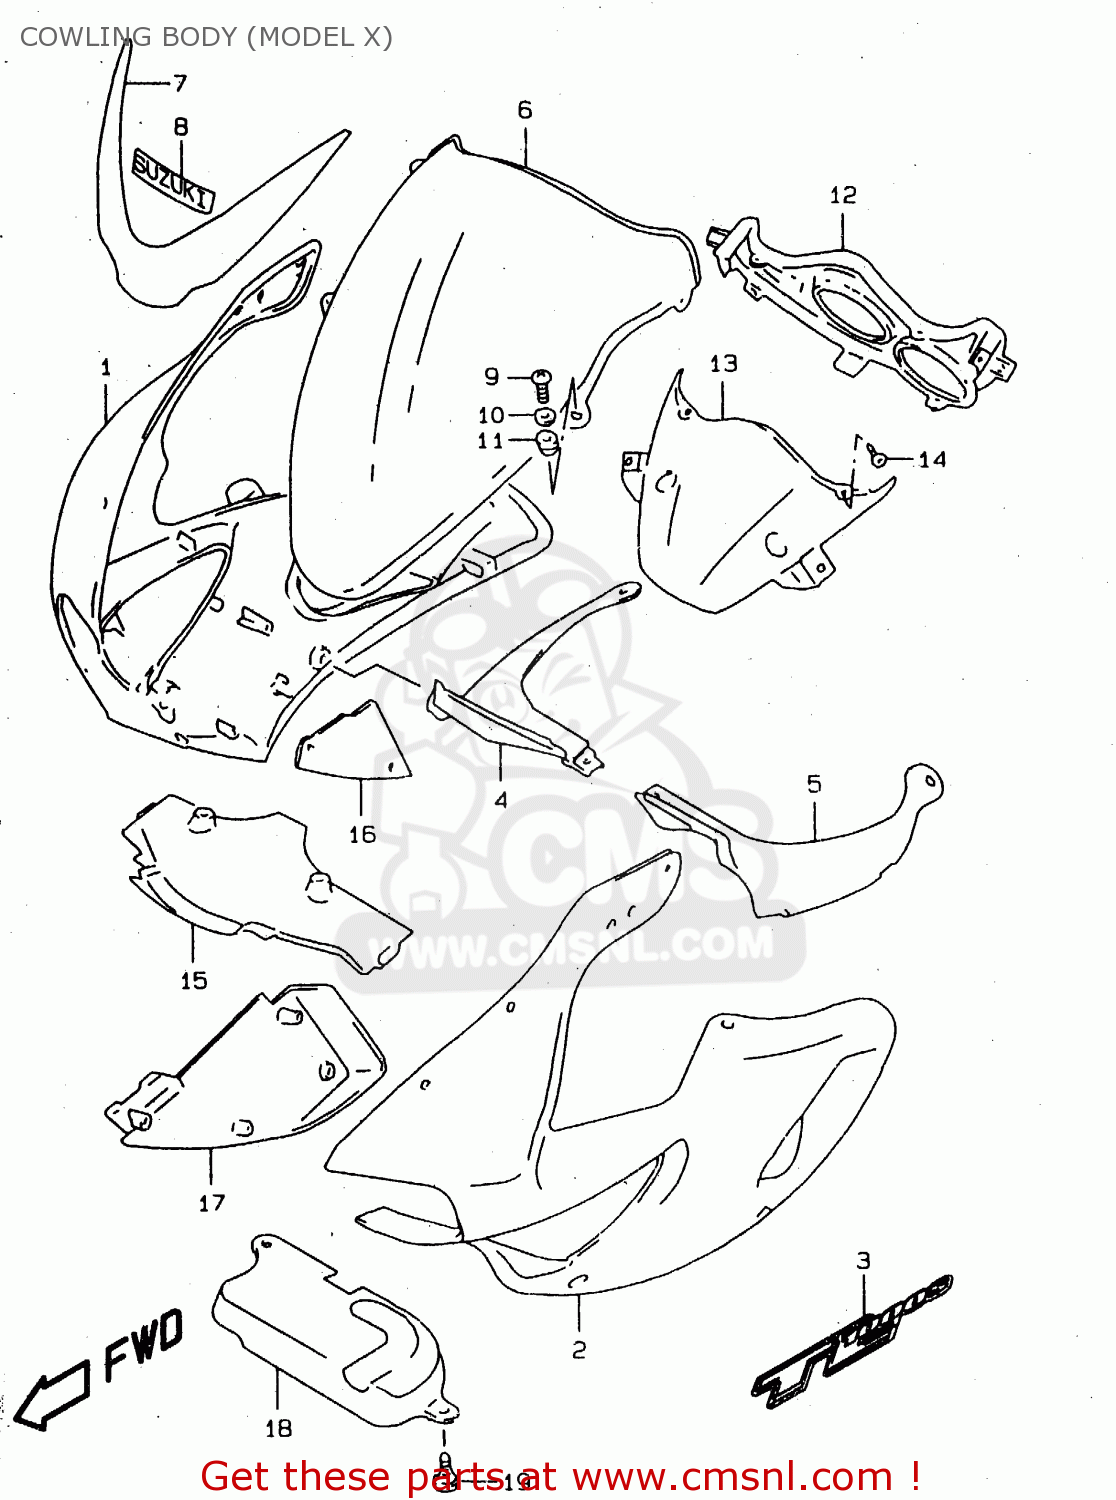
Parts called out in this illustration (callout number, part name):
1	COWLING,SIDE,R(BLUE)
2	COWLING,SIDE,L(BLUE)
3	EMBLEM,COWLING SIDE
4	PANEL,SIDE,R
5	PANEL,SIDE,L
6	WINDSCREEN(SILVER)
7	TAPE,WINDSCREEN
8	EMBLEM(SILVER)
9	SCREW(5X14)
10	WASHER
11	NUT
12	PANEL,METER
13	PANEL,FR
14	CLIP(BLACK)
15	COWLING,CTR LWR
16	COWLING,INNER,R
17	COWLING,INNER,L
18	COVER,COWLING FR LWR
19	BOLT
